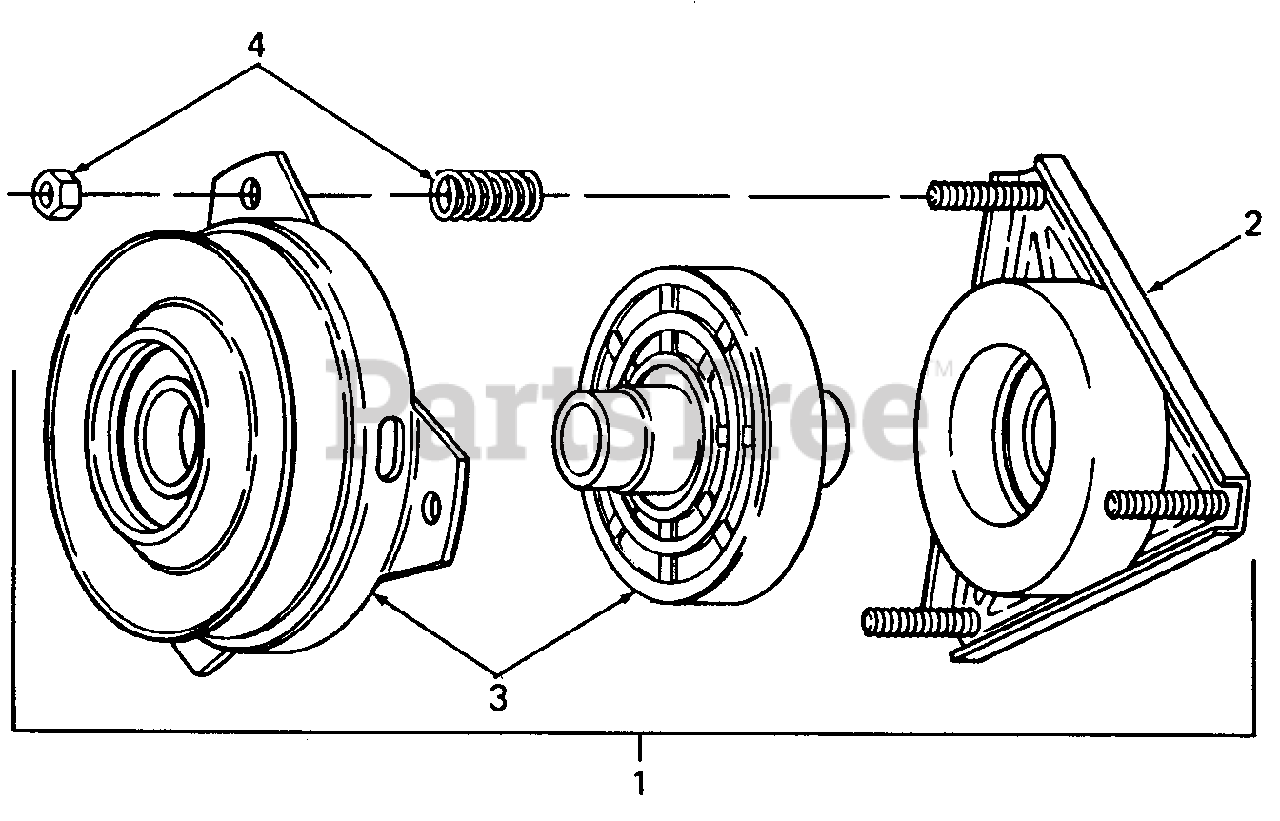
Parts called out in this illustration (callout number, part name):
1	Clutch Assy, PTO
2	Field Assy
3	Kit, Rotor & Armature
4	Mounting Accessories Hex Nuts Springs
